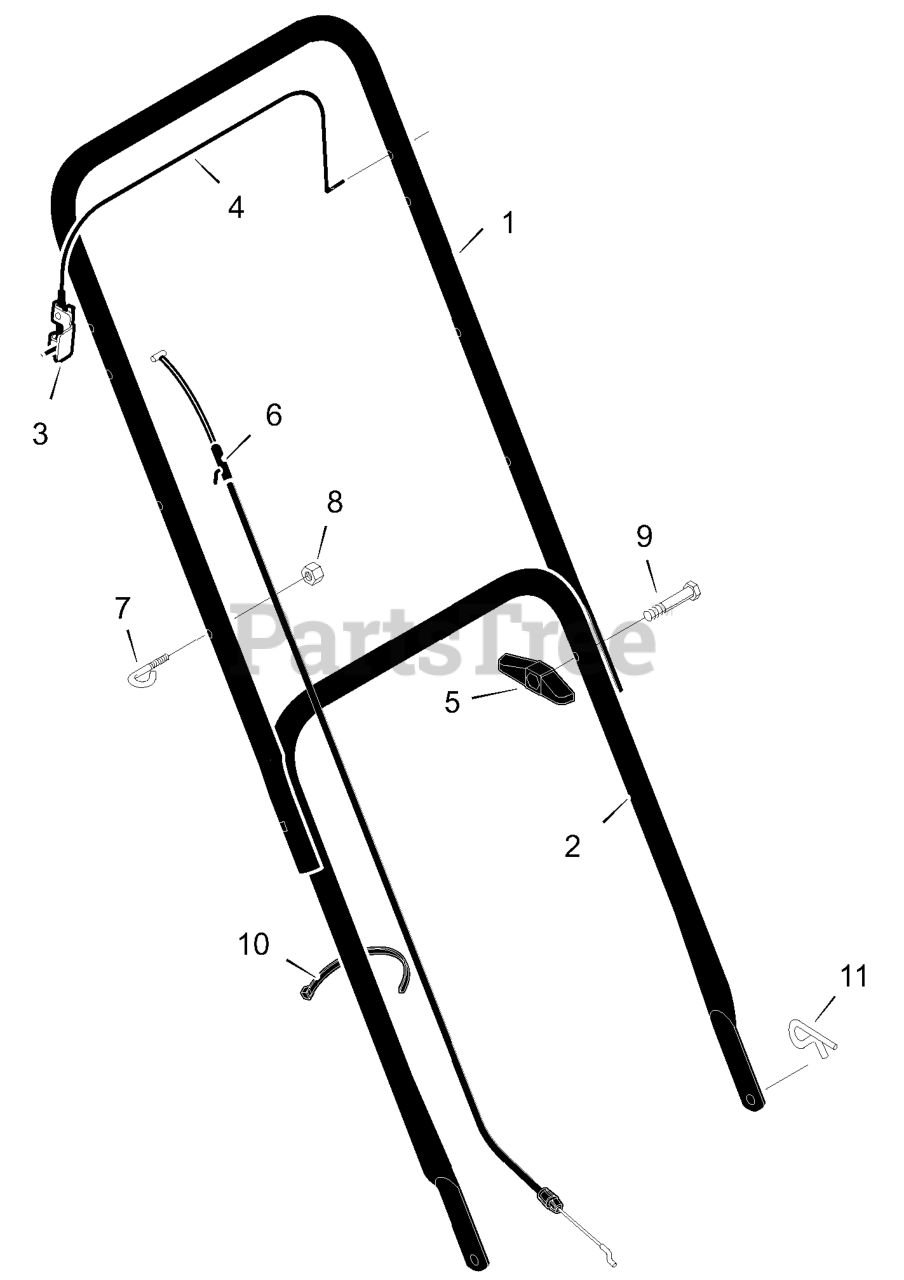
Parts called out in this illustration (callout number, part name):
1	Handle, Upper (Black)
2	Handle, Lower (Black)
3	Bracket, Stop Lever
4	Lever, Stop
5	Knob, Plastic
6	Engine Stop Cable
7	Guide, Rope
8	Locknut
10	Fastener, Cable
11	Pin, Hair
